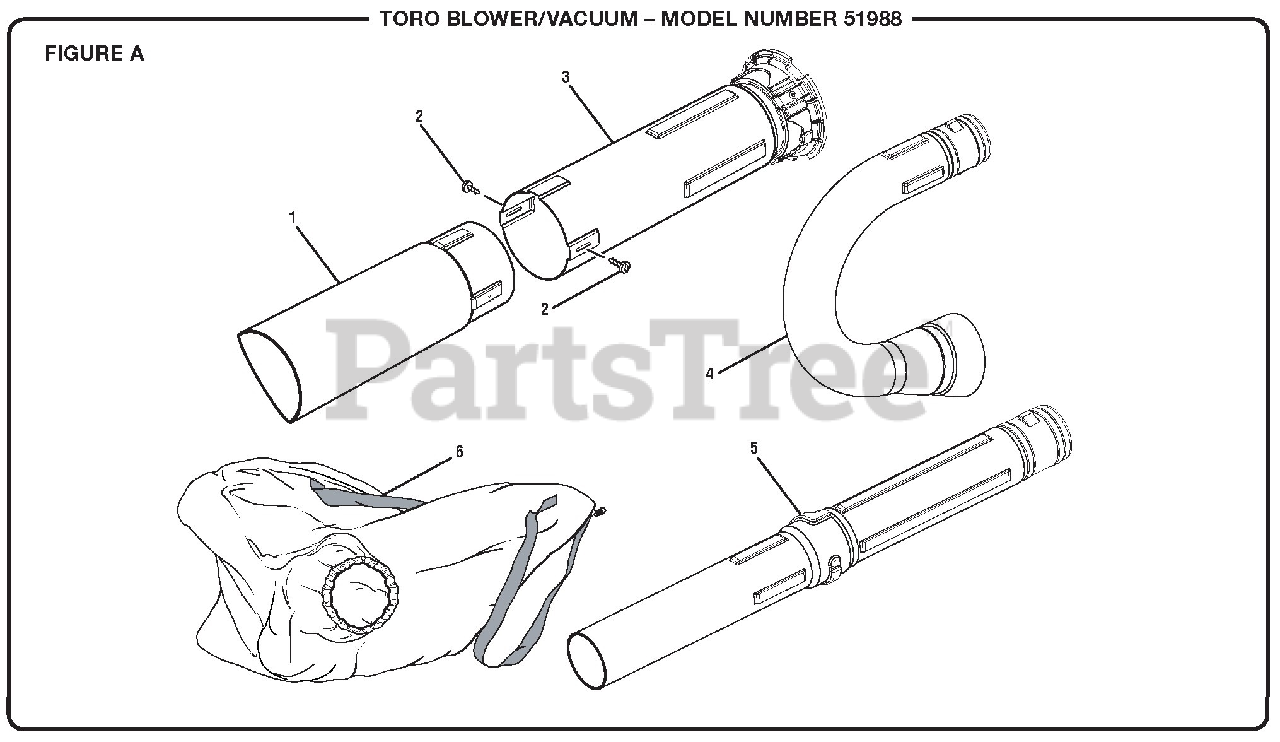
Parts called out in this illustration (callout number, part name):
1	Lower Vacuum Tube
2	Screw (#10-14 x 1/2 in., T25 Torx Hd.)
3	Upper Vacuum Tube
4	Vacuum Bag Adaptor
5	Blower Tube Assembly
6	Vacuum Bag Assembly
